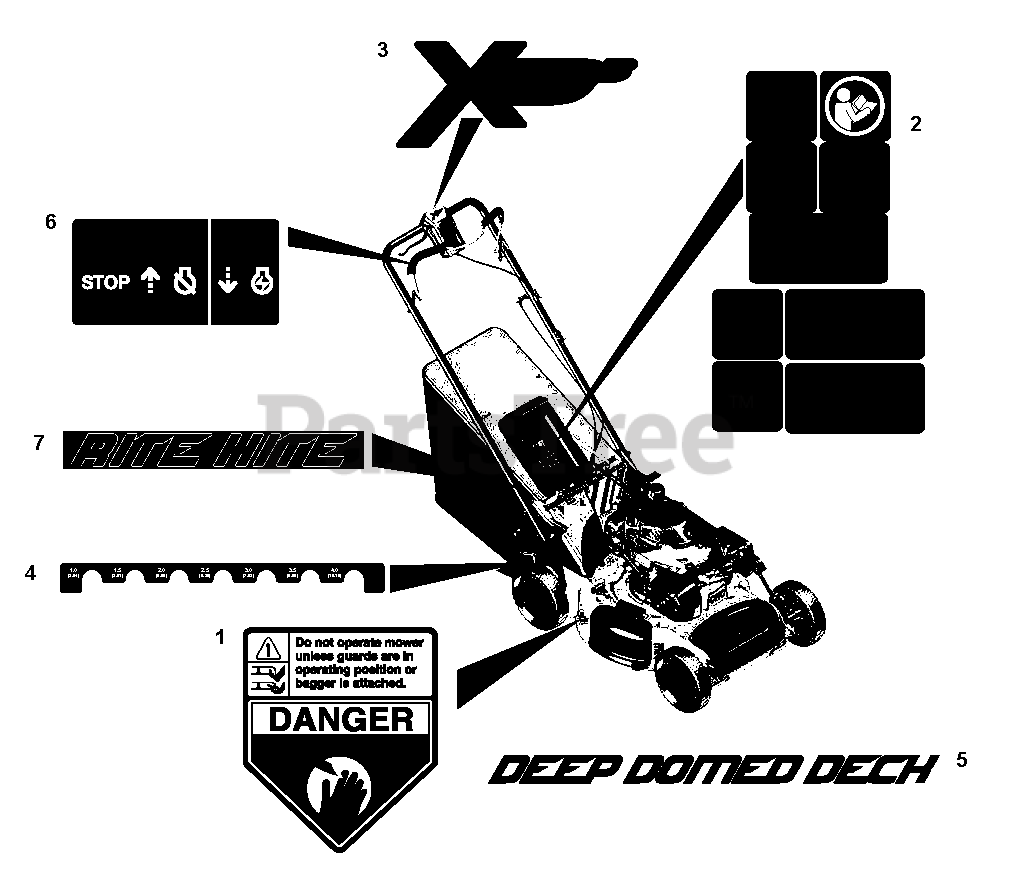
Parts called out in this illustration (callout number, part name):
1	Decal, Danger
2	Decal, Main Safety
3	Decal, Gravely XD3 Style (911172)
4	Decal, HOC (Height of Cut)
5	Decal, Deep Dome Deck
6	Decal, Engine Control
7	Decal, Rite Hite
